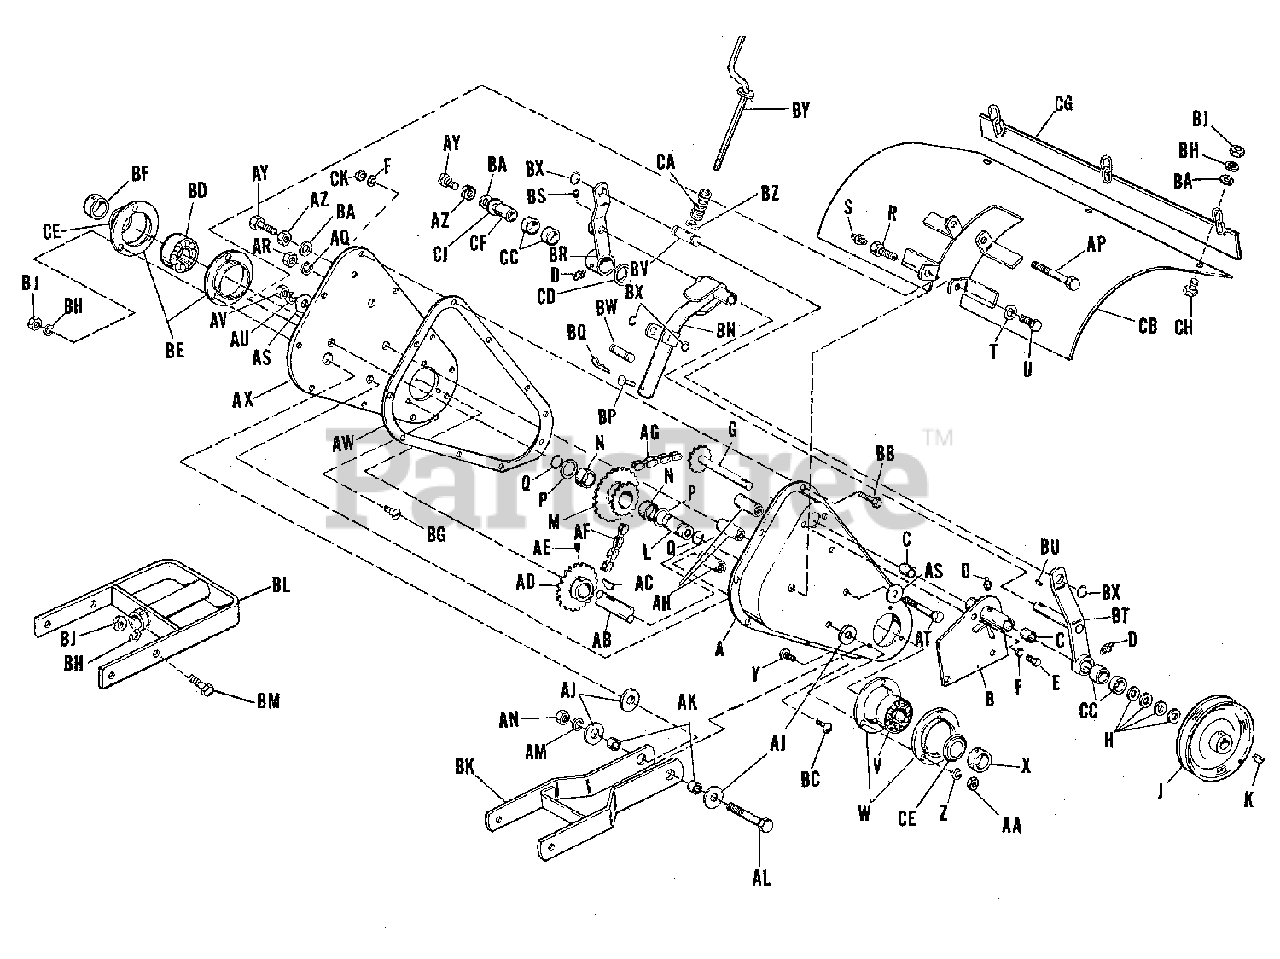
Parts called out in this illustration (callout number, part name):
A	GUARD ASSEMBLY, Chain
B	SUPPORT ASSEMBLY, Bearing Housing
C	BEARING, Needle
D	FITTING, Grease
E	CAPSCREW, Hex, 5/16-18NC x 3/4"
F	WASHER, Lock, 5/16"
G	DRIVE SHAFT ASSEMBLY
J	PULLEY, Drive
K	KEY, Woodruff
L	SPACER, Intermediate
M	SPROCKET ASSEMBLY
N	BEARING, Roller
Q	RING, Retaining
S	FITTING, Grease
T	WASHER, Plain, 7/16"
U	CAPSCREW, Hex, 1/2"-20 x 1-3/4"
W	FLANGE, Bearing
X	COLLAR, Bearing
Y	BOLT, Carriage, 3/8"-16 x 3/4" Lg.
Z	WASHER, Lock, 3/8"
AA	NUT, Hex, Full, 3/8"-16
AB	SHAFT, Tine
AC	KEY, Hi-Pro, 1/4" x 7/8"
AE	SCREW, Set, Cup Point, Socket Head, 5/16"-18 x 5/16"
AF	CHAIN, Rotor
AG	CHAIN, Drive
AH	SPACER, Guard
AL	CAPSCREW, Hex, 7/16"-14 4-1/2"
AM	WASHER, Lock, 7/16"
AN	NUT, Hex, Full, 7/16"-14
AP	CAPSCREW, 7/16"-14 x 4" Lg.
AQ	WASHER, Lock, 7/16"
AR	NUT, Hex, Full, 7/16"-14
AT	CAPSCREW, Hex, 7/16"-14 x 3-3/4" Lg.
AU	WASHER, Lock, 7/16"
AV	NUT, Hex, Full, 7/16"-14
AX	PLATE ASSEMBLY
AY	CAPSCREW, Hex, 3/8"-24 x 2-1/2" Lg.
AZ	NUT, Hex, Jam, 3/8"-24
BA	WASHER, Plain, 3/8"
BB	CAPSCREW, Hex, 5/16"-18 x 5/8" Lg.
BC	BOLT, Carriage, 5/16"-18 x 5/8" Lg.
BE	FLANGE, Bearing
BF	COLLAR, Bearing
BG	BOLT, Carriage, 3/8"-16 x 3/4" Lg.
BH	WASHER, Lock, 3/8"
BJ	NUT, Hex, Full, 3/8"-16
BK	FRAME ASSEMBLY
BL	TILLER SOCKET ASSEMBLY
BM	CAPSCREW, Hex, 3/8"-16 x 1" Lg.
BN	LIFT BAR ASSEMBLY
BP	PIN
BQ	CLIP, Spring
BR	LEVER ASSEMBLY, R.H. Side, Belt Tension
BS	SCREW, Set, Cup Point, Socket Head, 5/16"-18 x 5/16"
BT	LEVER ASSEMBLY, L.H. Side, Belt Tension
BU	KEY, Woodruff
BV	PIVOT, Upper
BW	PIVOT, Lower
BX	RING, Retaining
BY	SCREW ASSEMBLY, Adjusting
BZ	WASHER, Plain, 5/16"
CB	DEFLECTOR ASSEMBLY
CD	WASHER, Thrust
CG	FLAP ASSEMBLY
CH	CAPSCREW, Hex, 3/8"-16 x 7/8" Lg.
CJ	WASHER
CK	NUT, Hex, Lock, 5/16"-18 NC
